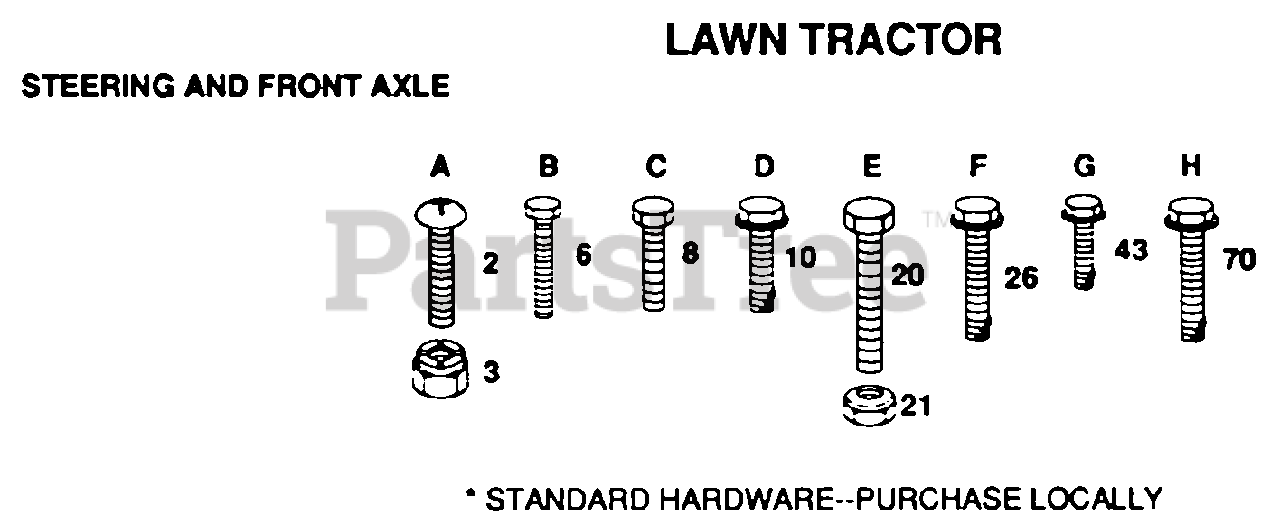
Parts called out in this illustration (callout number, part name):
2	SCREW
6	SCREW LT
10	SCREW LT
26	SCREW
43	SCREW LT
70	SCREW SPECIAL
